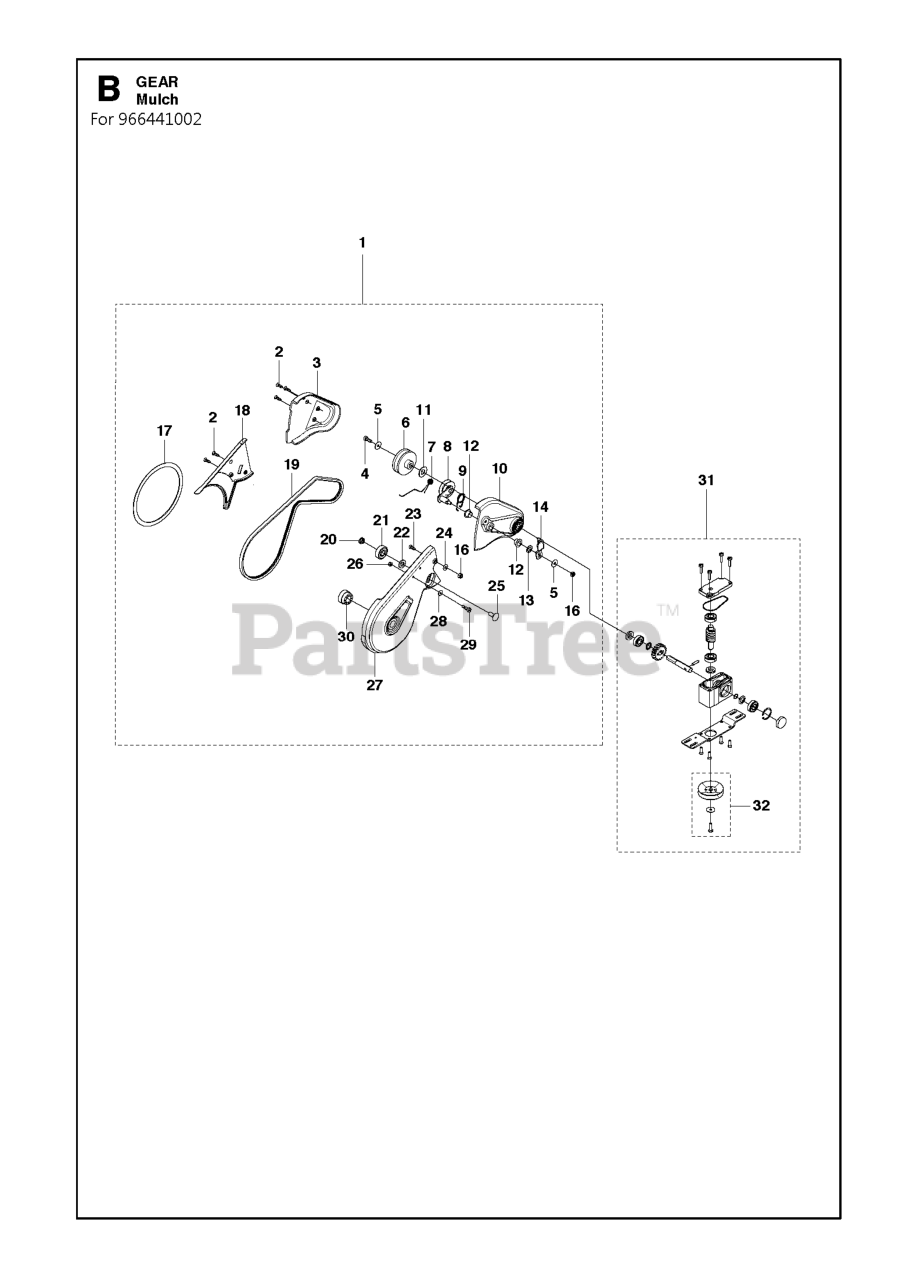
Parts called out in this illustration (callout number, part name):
5	WASHER 19X6X1
16	NUT FLANGE - M6
21	BALL BEARING 6201-2RS1
